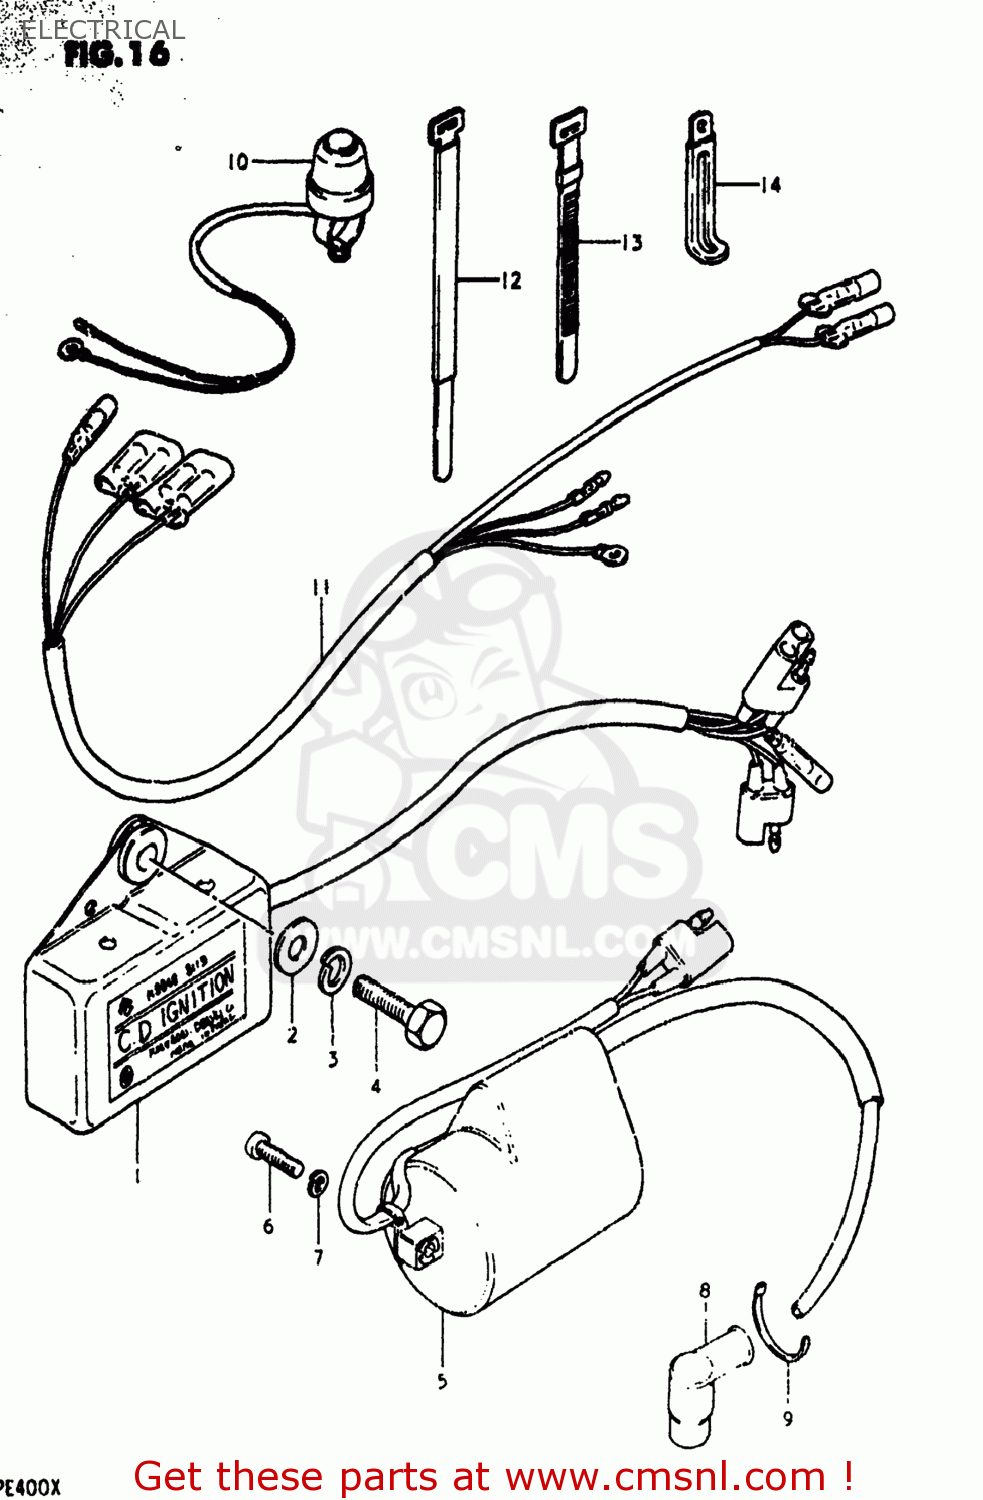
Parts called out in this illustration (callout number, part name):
1	CDI UNIT
2	WASHER(6.5X16X1.2)
3	LOCK WASHER
4	BOLT
5	COIL ASSEMBLY,IGNITION
6	SCREW 5X20
7	LOCK WASHER
8	CAP,SPARK PLUG
9	CLAMP
10	SWITCH ASSEMBLY
11	HARNESS,WIRING
12	CLAMP
13	CLAMP(L:120)
14	CLAMP
